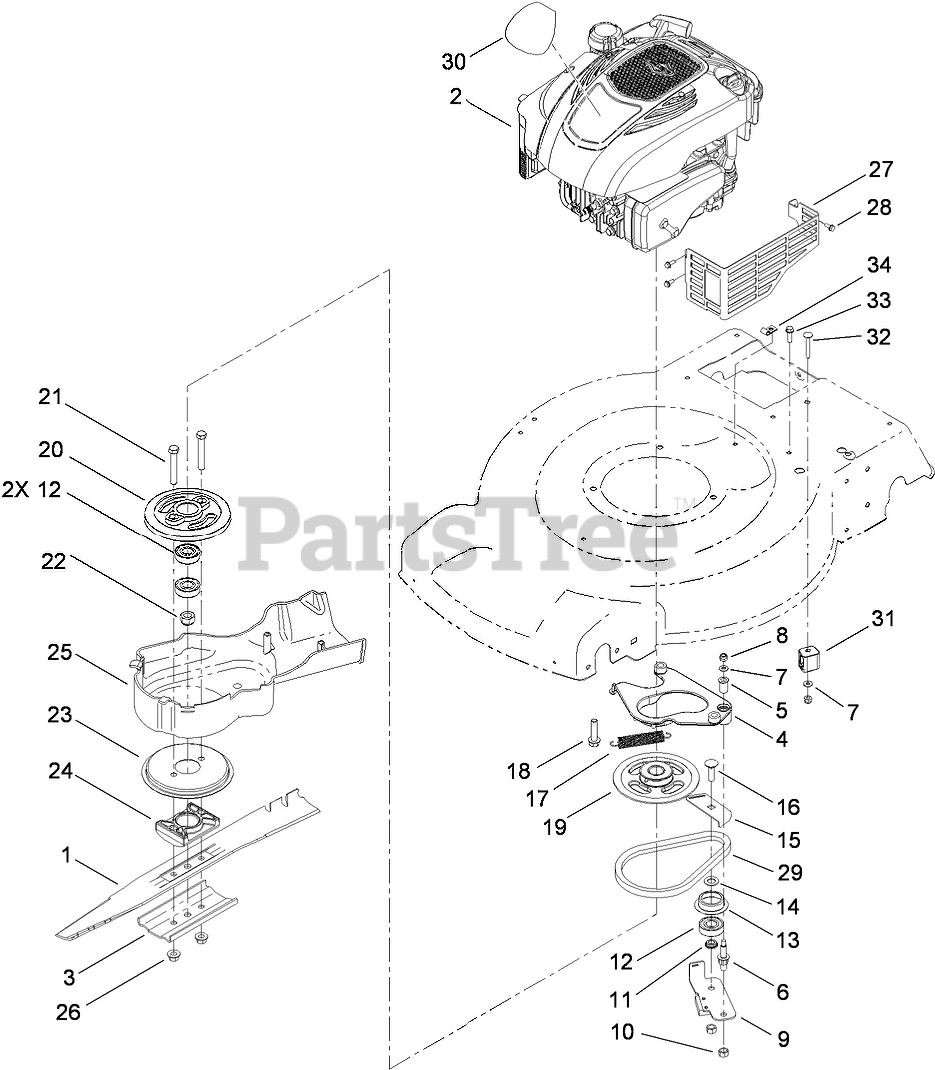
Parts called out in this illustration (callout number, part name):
1	BLADE
3	SUPPORT-BLADE
4	PLATE-ANCHOR
5	BUSHING
6	BOLT-SHOULDER
7	WASHER-FLAT
8	NUT-LOCK, NI
9	BRAKE ARM ASM
11	SPACER-BEARING
12	BEARING-BALL
13	RETAINER-BELT
14	WASHER-PLAIN
15	PLATE-GUIDE
16	BOLT-CARR
17	SPRING-TENSION, BRAKE
18	SCREW-HWH
19	PULLEY
20	DRUM
21	SCREW-HH
22	NUT-HEX
23	DISC
24	SUPPORT-BLADE
26	NUT-LOCK
27	SHIELD-MUFFLER
28	SCREW-TAPTITE
29	BELT
31	ANCHOR-CABLE
32	SCREW-CARR
33	SCREW-HWH
34	CLIP-CLOSED, INSULATED
